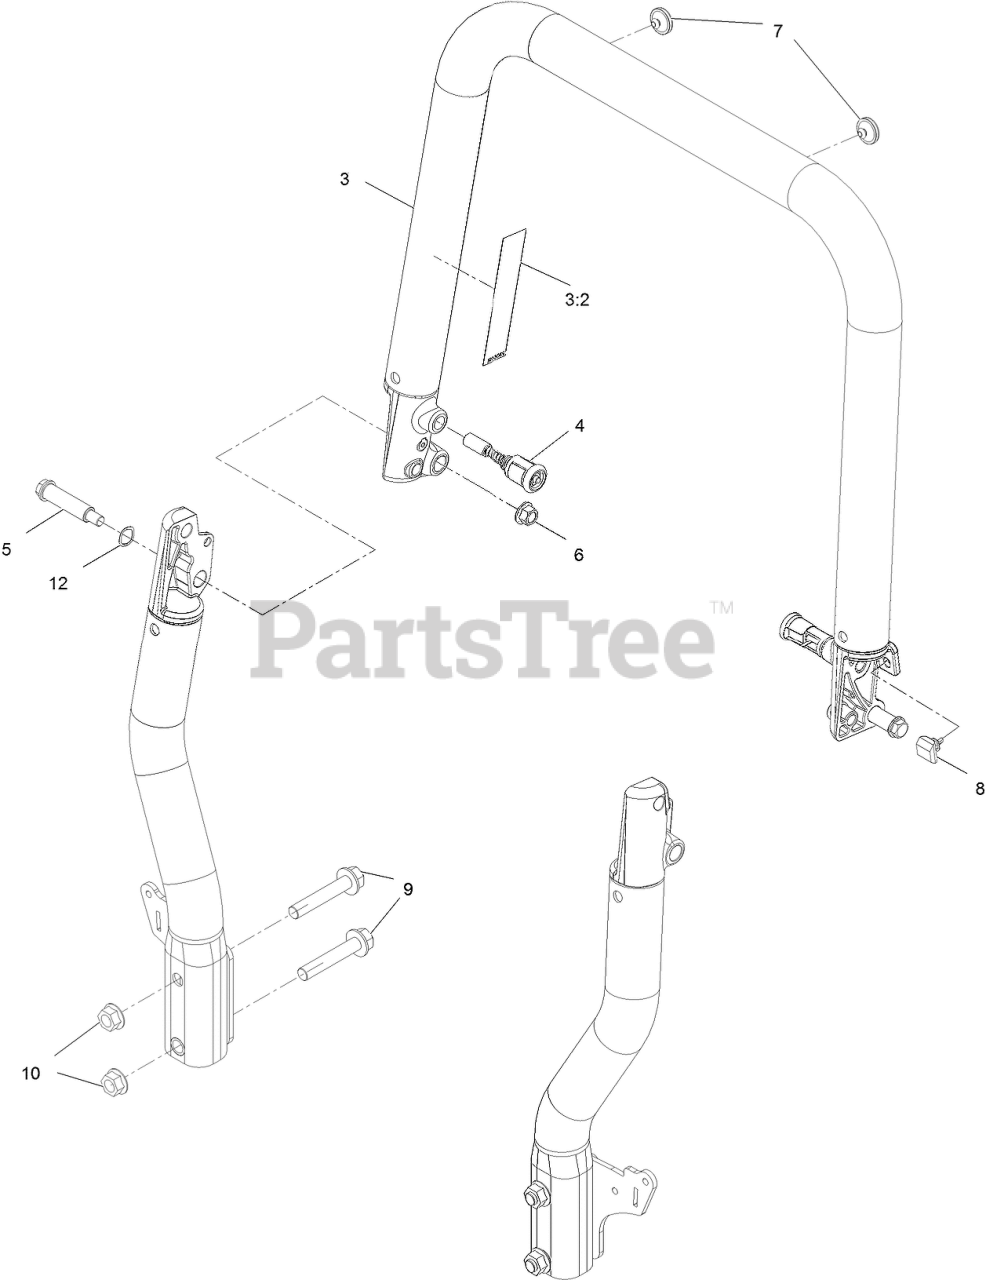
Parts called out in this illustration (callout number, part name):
3	TOP TUBE ASM
3:2	DECAL-WARNING
4	PIN-SPRING
5	BOLT-SHOULDER
6	Nut-Lock 1/2-13
7	BUMPER-ROPS
8	BUMPER-ROPS
9	SCREW-HHF
10	NUT-FLANGE
12	WASHER-WAVE
